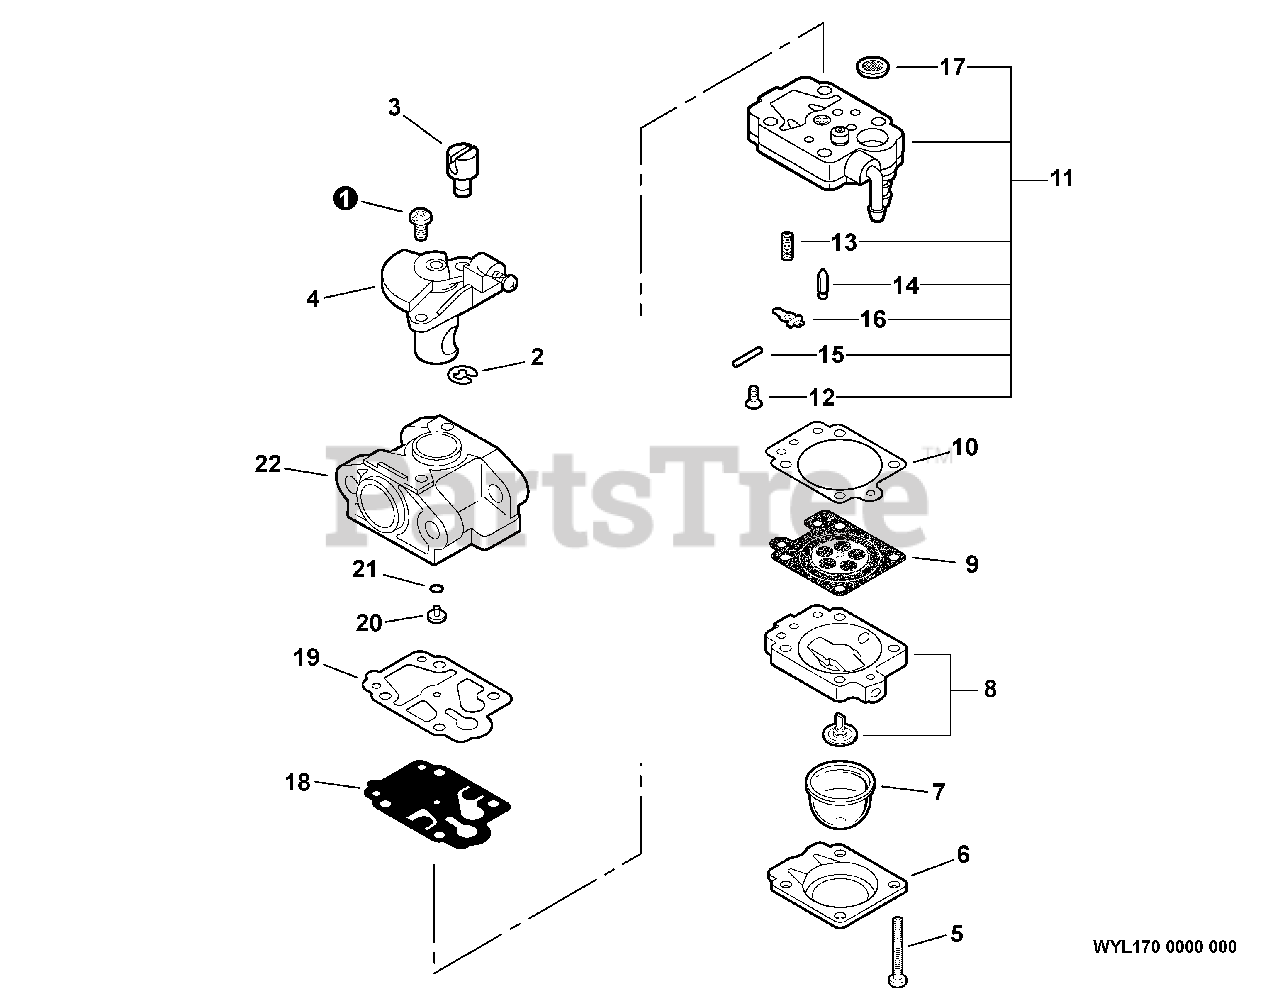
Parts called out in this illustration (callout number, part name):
2	RING, RETAINING
4	THROTTLE VALVE ASSY
5	SCREW, PUMP COVER
6	RETAINER, PURGE BULB
7	BULB, PURGE
8	PURGE BASE ASSY
9	DIAPHRAGM, METERING
10	GASKET, METERING
11	BASE, PURGE
12	SCREW, METERING LEVER PIN
13	SPRING, METERING LEVER
14	VALVE, INLET NEEDLE
15	PIN, METERING LEVER
16	LEVER, METERING
17	STRAINER
18	DIAPHRAGM, PUMP
19	GASKET, PUMP
20	JET, MAIN
22	BODY, CARBURETOR
